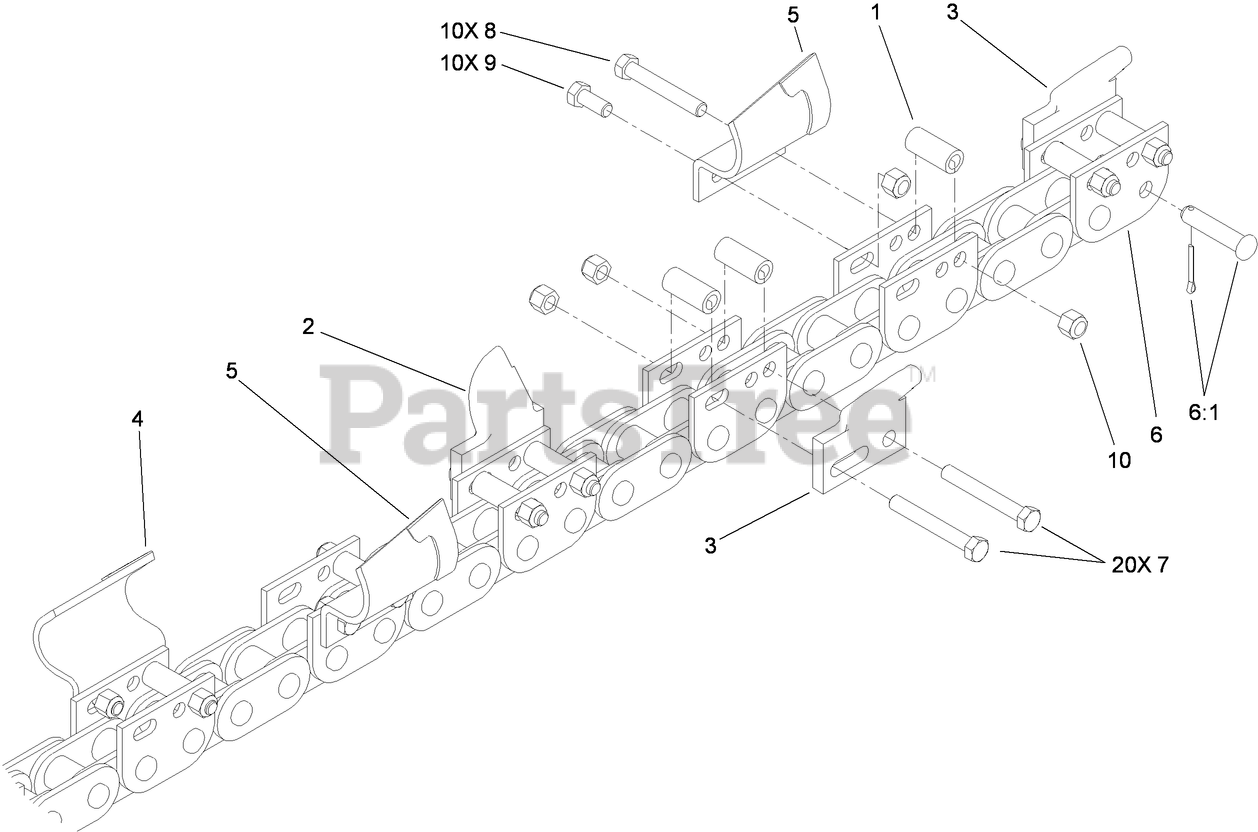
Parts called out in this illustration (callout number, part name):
1	SPACER-TUBE
2	TOOTH- ROCK, LH
3	TOOTH-ROCK, RH
4	TOOTH-SOIL, LH
5	TOOTH-SOIL, RH
6	CHAIN-BARE, 40 STATION
6:1	PIN-CONNECTING,
7	SCREW-HH
8	SCREW-HH
9	SCREW-HH
10	NUT-LOCK
